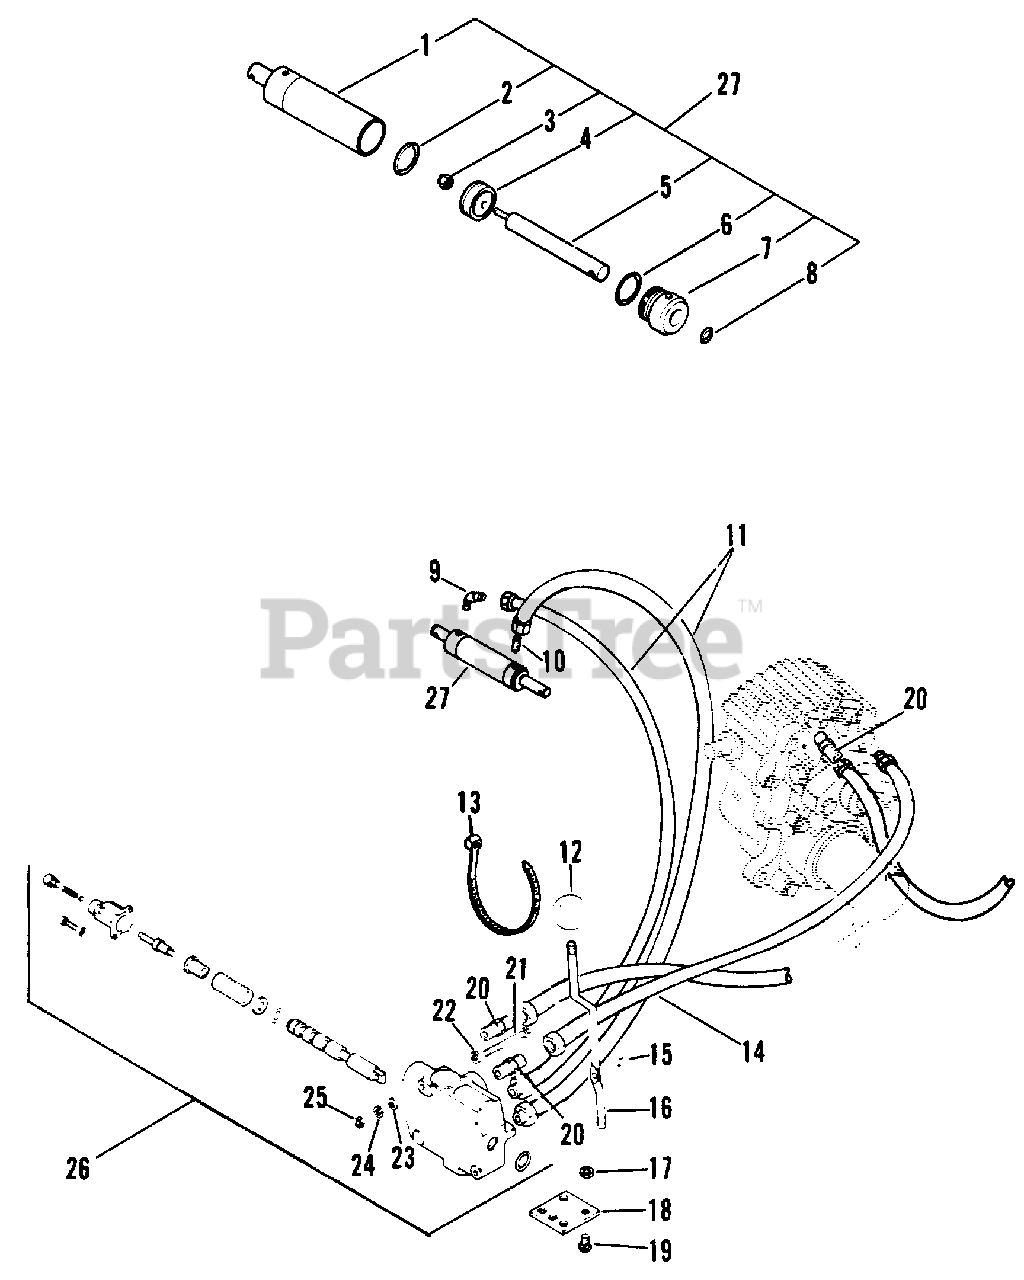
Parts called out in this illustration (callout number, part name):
1	Cylinder
2	O-Ring, 1-5/8 Nom. I.D.
3	Nut, Lock 3/8-24
4	Piston
5	Rod
6	O-Ring, 2-1/8 Nom. I.D.
7	Rod Cap
8	O-Ring, 1 Nom. I.D.
9	Adapter 9/16 to 1/4
10	Adapter
11	Hydraulic Hose
12	Knob, Steering Lock
13	Tie, Cable
14	Hydraulic Hose
15	Pin, Groove 1/4 x 3/4 Type B
16	Control Rod
17	Nut, Lock 5/16-18
18	Pivot Bracket
19	Bolt, 5/16-18 x .625 Rd Hd Sq Nk
20	Connector
21	Bolt, Hex 1/4-20 x 2.25
22	Washer, Flat .281 x .625 x .065
23	Washer, .245/.265 x .562 x .125
24	Washer, Lock 1/4 Reg.
25	Nut, Hex 1/4-20
26	Hydraulic Control Valve
27	Cylinder Assembly
